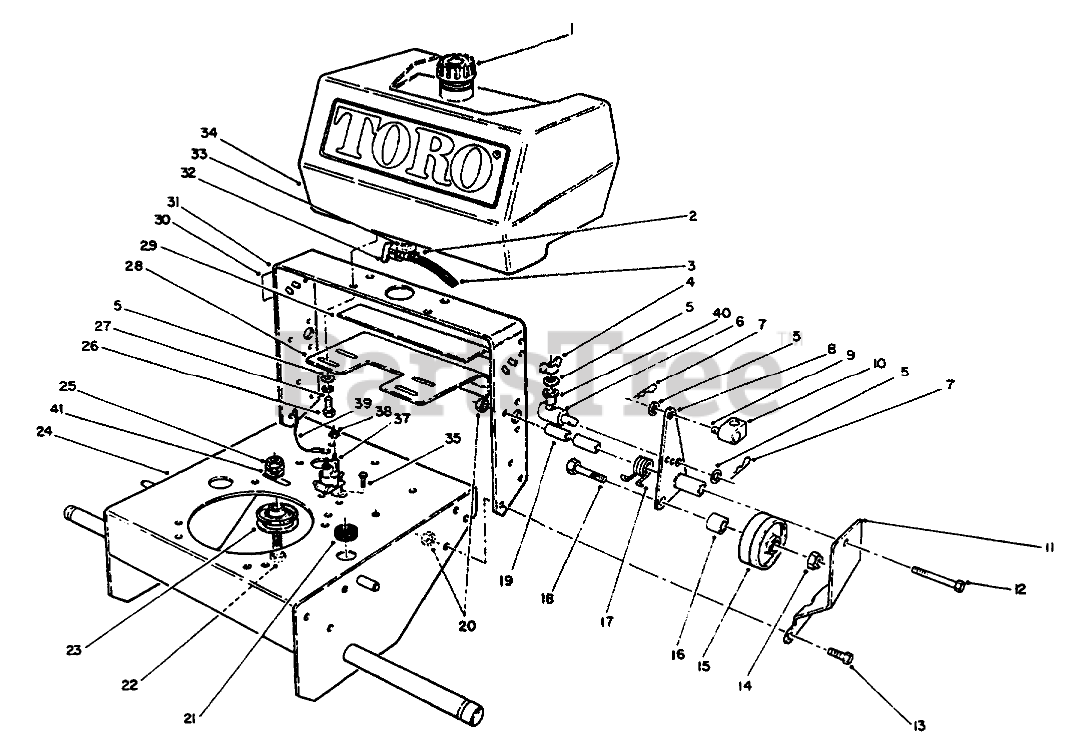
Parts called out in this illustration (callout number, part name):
1	GAS CAP ASM
2	CLAMP-HOSE
3	HOSE-FUEL
4	NUT-WING
5	WASHER-PLAIN
6	FITTING-ROD
7	PIN-COTTER
8	BRACKET-Idler, LH
9	PIN-CLEVIS
10	FITTING-ROD
11	Bracket-LH
12	SCREW-HH
13	SCREW-HH
14	NUT-LOCK, NI
15	IdlerWheel
16	WHEEL IDLER SPACER
17	SPRING-TORSION, LH
18	SCREW-LEVELER
19	SPACER-PIVOT, IDLER
20	NUT-LOCK, NI
21	GROMMET
22	SCREW-HH
23	PULLEY-IDLER
24	FRAME
25	NUT-HF
26	SCREW-HH
27	WASHER-LOCK
28	Plate
29	DECAL-GROUND SPEED
30	DECAL-FUEL SHUT OFF
31	Frame Rear
32	VALVE-FUEL
33	O-RING
34	Tank-Fuel
35	SCREW
37	SOLENOID
38	NUT-KEPS
39	WIRE-SOLENOID/STARTER
40	BUSHING-NYLON
41	WASHER-FLAT
